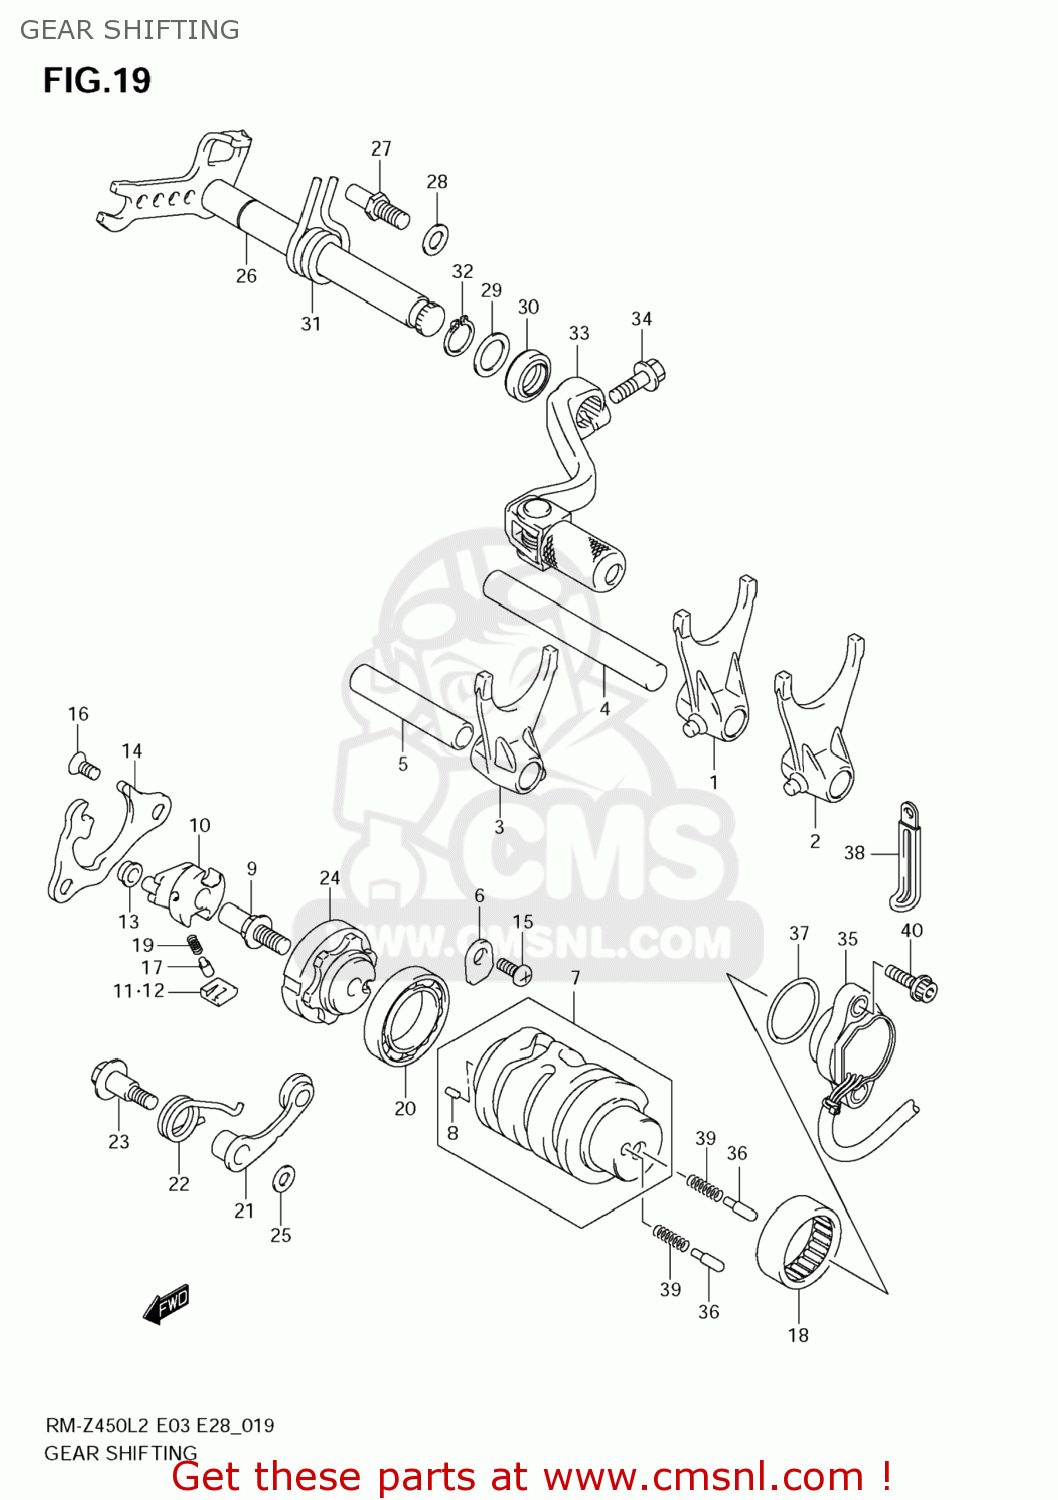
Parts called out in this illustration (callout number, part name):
1	FORK,GEAR SHIFT NO.1
2	FORK,GEAR SHIFT NO.2
3	FORK,GEAR SHIFT NO.3
4	SHAFT,GEAR SHIFT FORK NO.1
5	SHAFT,GEAR SHIFT FORK NO.2
6	RETAINER
7	CAM,GEAR SHIFT
8	PIN
9	PIN,GEAR SHIFT CAM
10	SHIFTER,GEAR SHIFT CAM
11	PAWL,GEAR SHIFT NO.1
12	PAWL,GEAR SHIFT NO.2
13	ROLLER,GEAR SHIFT CAM SHIFTER
14	LIFTER,GEAR SHIFT PAWL
15	SCREW(6X12)
16	SCREW(6X12)
17	PIN
18	BEARING(25X32X12)
19	SPRING
20	BEARING
21	STOPPER,GEAR SHIFT CAM
22	SPRING,GEAR SHIFT CAM STOPPER
23	BOLT,SHIFT CAM STOPPER
24	PLATE,GEAR SHIFT CAM STOPPER
25	WASHER
26	SHAFT,GEAR SHIFT
27	STOPPER,GEAR SHIFT ARM
28	SHIM(8.8X14X1)
29	SHIM(14X20X1)
30	SEAL,OIL(14X22X7.3)
31	SPRING
32	CIRCLIP
33	LEVER ASSY,GEA
34	BOLT
35	BASE ASSY,GEAR SHIFT TERMINAL
36	PIN(5X15.5)
37	O RING(D:2.4,ID:26.2)
38	CLAMP(L:45)
39	SPRING
40	BOLT
